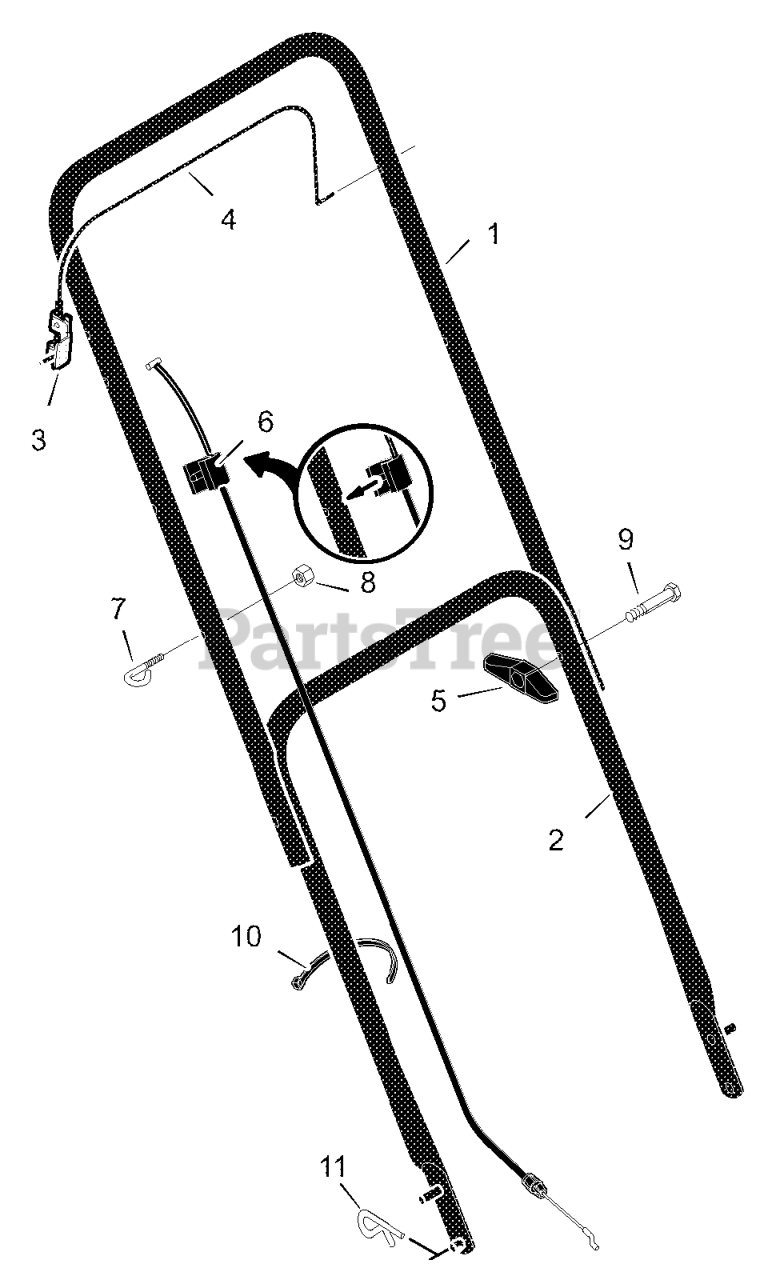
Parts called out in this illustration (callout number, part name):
1	Handle, Upper (Black)
2	Handle, Lower (Black)
3	Bracket, Stop Lever
4	Lever, Stop
5	Knob, Plastic
6	Engine Stop Cable
7	Guide, Rope
8	Locknut
10	Fastener, Cable
11	Pin, Hair
